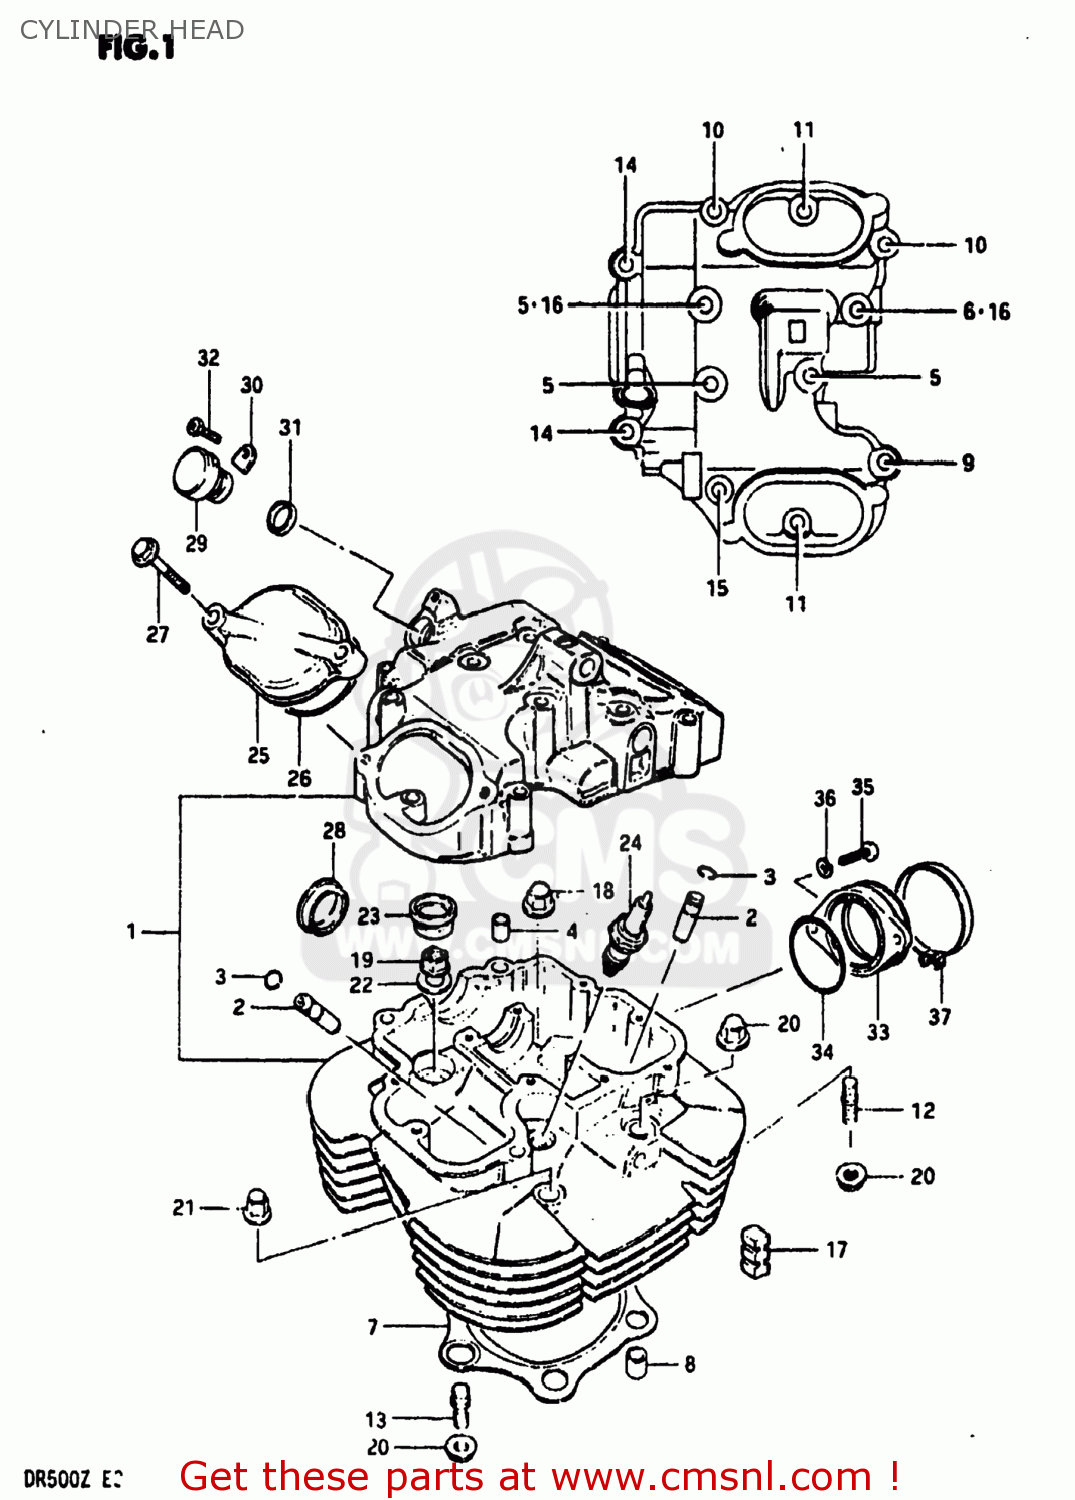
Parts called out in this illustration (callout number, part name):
1	HEAD,CYLINDER (4-VALVE)
2	GUIDE,VALVE
3	RING,SNAP
4	PIN(6.2X8X11)
5	BOLT (6X60)
6	BOLT 6X55
7	GASKET,CYLINDER HEAD (NAS)
8	PIN
9	BOLT ,6X50
10	BOLT,UNDER
11	BOLT
12	STUD
13	STUD
14	BOLT
15	BOLT (6X60)
16	GASKET (NAS)
17	PAD,CYLINDER
18	NUT
19	NUT
20	NUT
21	NUT
22	GASKET (NAS)
23	NUT,CYLINDER HEAD SEAL
24	SPARK PLUG D8EA
25	CAP,INSPECTION HOLE
26	O RING(D:2.4,ID:23)
27	BOLT
28	PLUG(OD:30)
29	PLUG,TACH GEAR SLEEVE HOLE
30	PLATE,TACH DRIVE GEAR SLEEVE
31	SEAL,TACHOMETER DRIVEN
32	SCREW(5X12)
33	PIPE,INTAKE
34	O-RING (D:2.4 ID:45.7)
35	SCREW
36	LOCK WASHER
37	CLAMP
